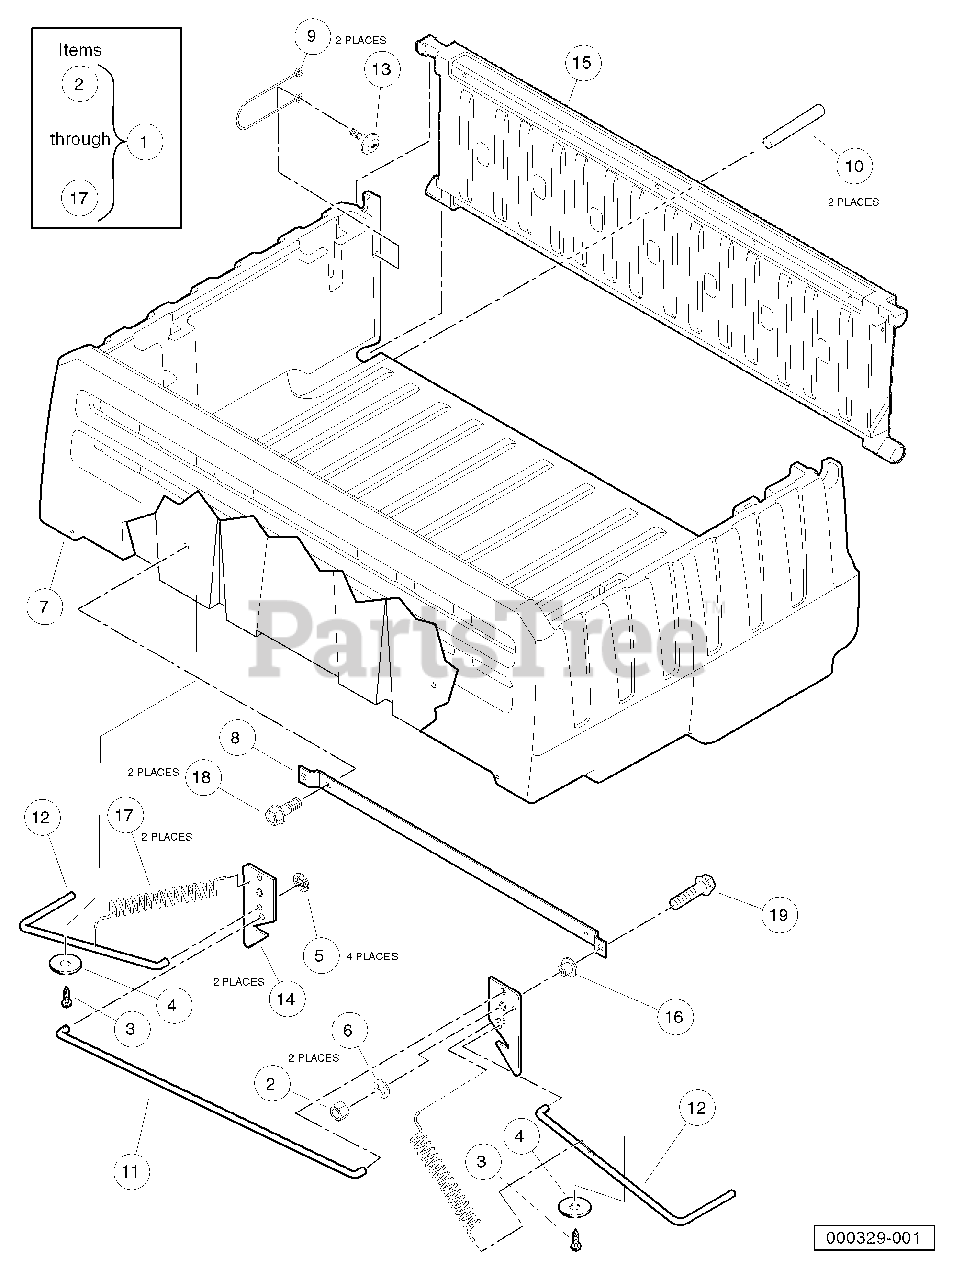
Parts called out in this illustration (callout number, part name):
1	Assembly, Bed
2	Locknut, 3/8-16 Dimpled
3	Screw, Hex Washer Head 1/4-14 X .75
4	Washer, 5/16 Type B Flat
5	Pushnut, 3/8
6	Washer, 3/8 Flat Type A
8	Support, Latch Link
9	Lanyard, Tailgate
10	Pin, Support
11	Rod, Long Link
12	Rod, Bed Lift, Short Bent
13	Bolt Lanyard
14	Catch, Tilt Bed
15	Tailgate, Husqvarna
16	Bearing, Bronze, 1/2x9/32
17	Spring, Tilt Latch 3.4 Lb/in
18	Screw, 1/4-20 X 1.0 Hex-Head Cap
19	Screw, 3/8-16 X 1.00 Hex-Head Cap
